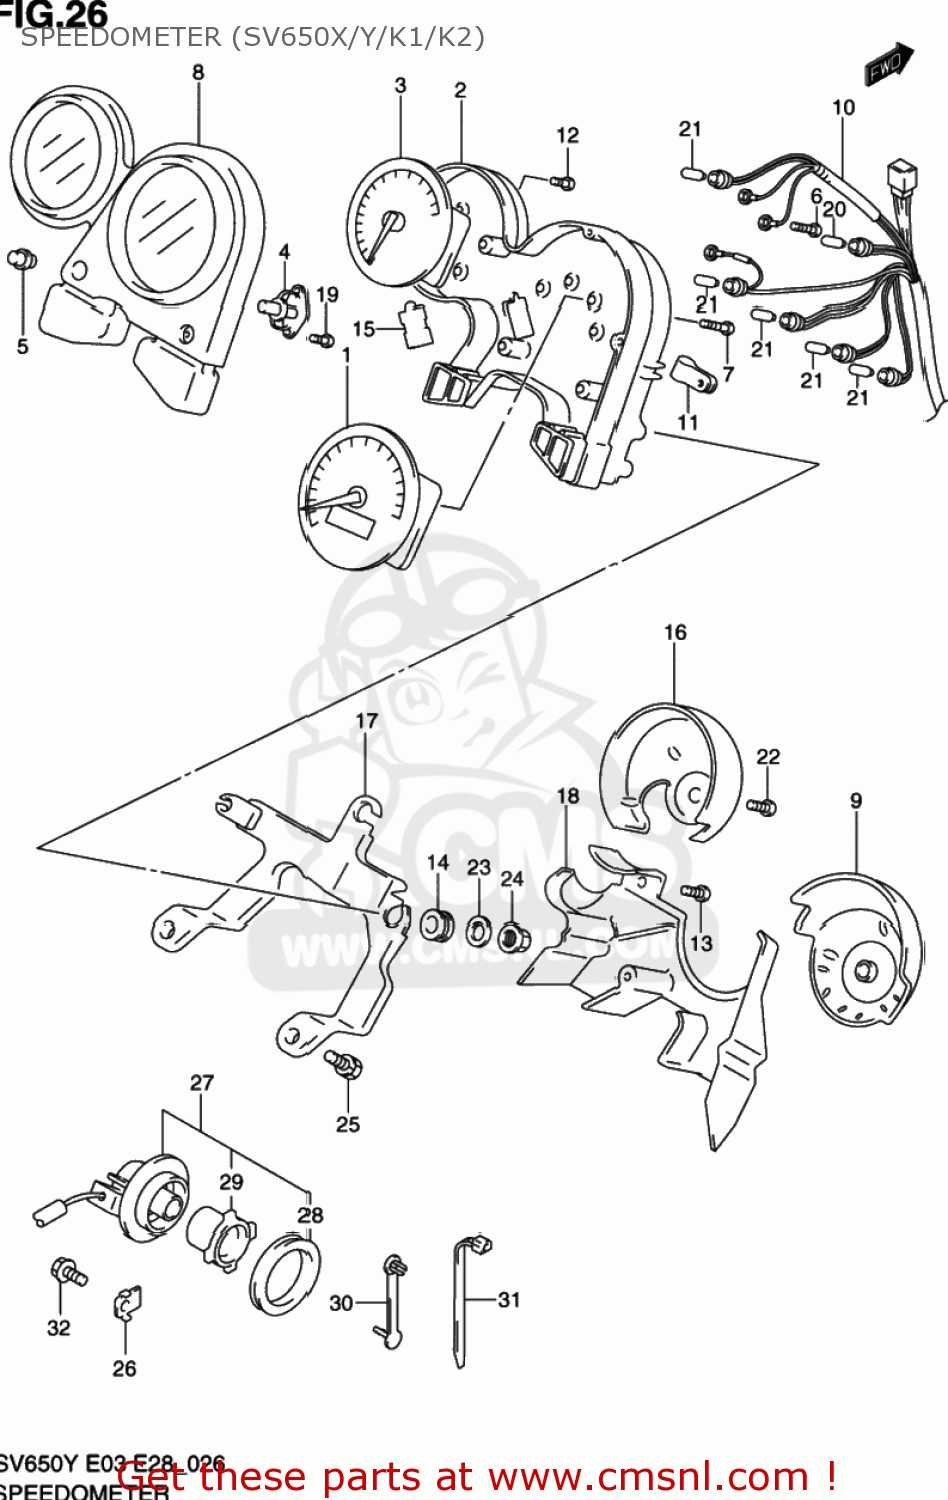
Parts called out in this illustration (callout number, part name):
1	SPEEDOMETER
2	LWR CASE
3	TACHOMETER
4	ATTACHMENT,SWITCH
5	SWITCH,GUM
6	SCREW,PAN HEAD(3X18)
7	SCREW,PAN HEAD(3X20)
8	UPR CASE
9	COVER ,SPEEDOMETER
10	CORD ASSY
11	CLAMP
12	SCREW(3X12)
13	SCREW,HEAD(4X16)
14	DAMPER
15	GROMMET
16	ORNAMENT,TACHOMETER
17	BRACKET
18	COVER
19	SCREW(3X10)
20	BULB(12V1.7W,T10,WB121)
21	BULB(12V1.7W,T6.5)
22	SCREW
23	WASHER(6.5X18X1)
24	NUT
25	BOLT
26	GUIDE,SENSOR LEAD
27	SENSOR,SPEED
28	SEAL,OIL(44X55X6)
29	ROTOR,SPEEDOMETER
30	CLAMP(L:33)
31	CLAMP(L:145)
32	BOLT
